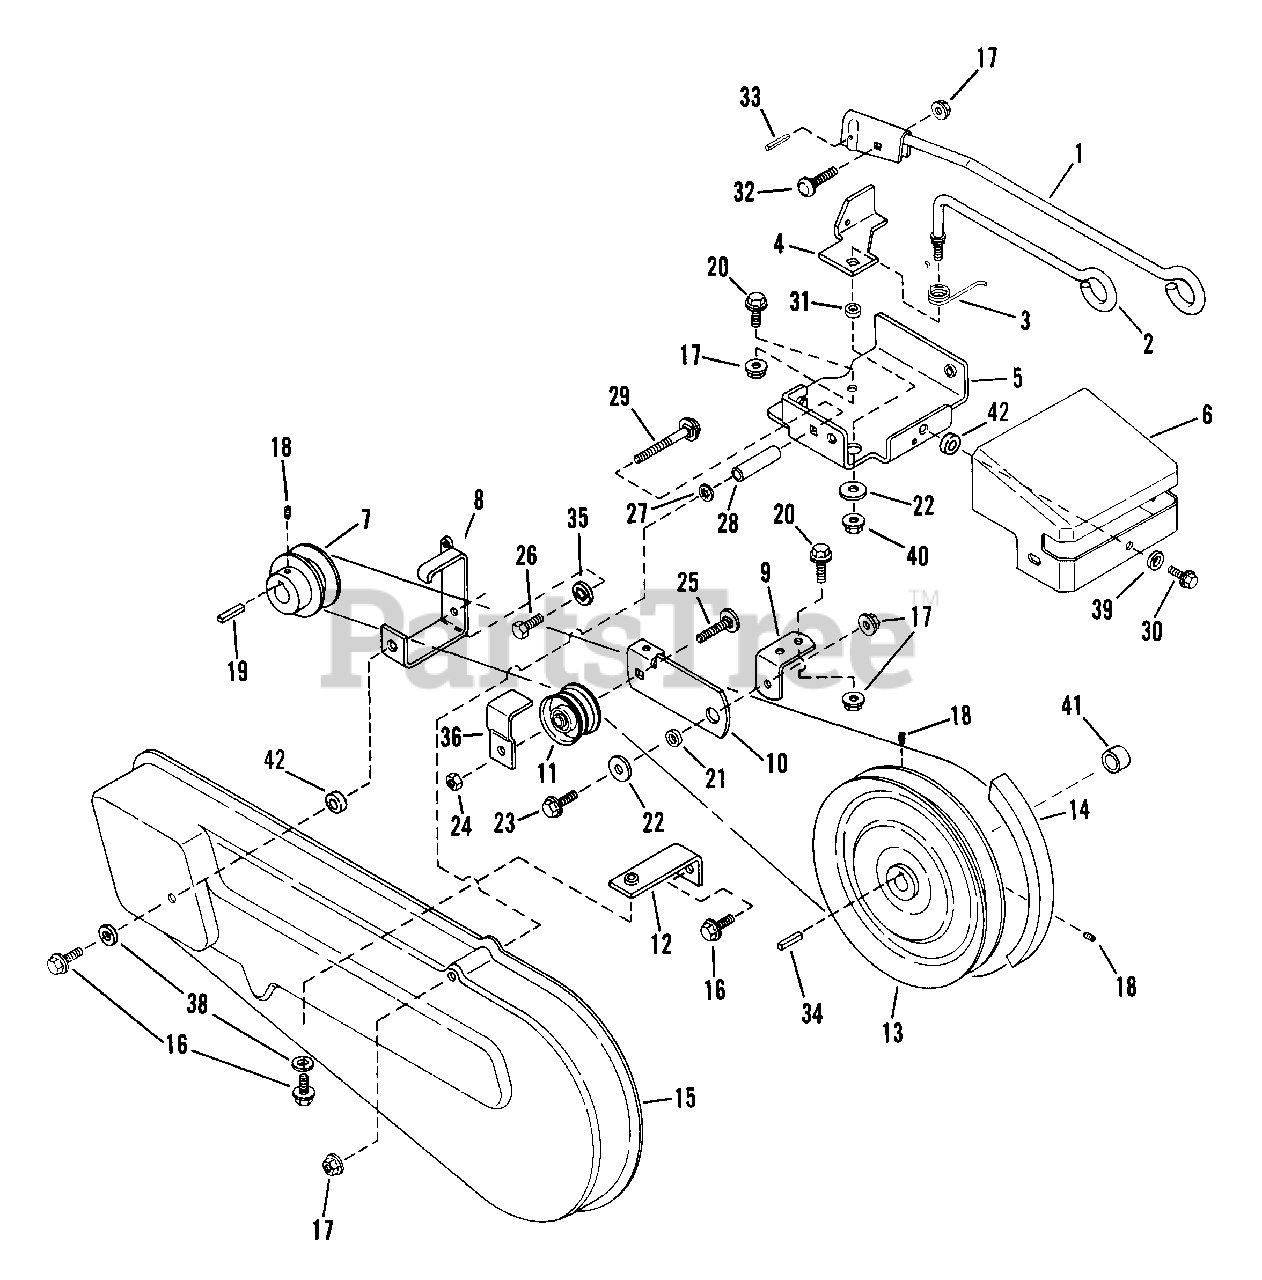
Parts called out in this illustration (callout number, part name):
1	LEVER, Shift
2	LEVER, Lockout
3	SPRING, Interlock
4	INTERLOCK, Shift
5	PLATE, Shift
6	COVER, Shift
7	PULLEY, Engine
8	GUIDE, Belt
9	BRACKET, Idler Pivot
10	BRACKET, Idler Arm
11	PULLEY, Idler
12	BRACKET, Belt Cover
13	PULLEY, Driven
14	BELT, Drive
15	COVER, Belt
16	SCREW, 5/16-18 x 1/2 Self-Tapping
17	NUT, 5/16-18 Hex Flange Lock
18	SCREW, 5/16-18 x 5/16" Hex Set
19	KEY, 3/16x3/16x1"
20	BOLT, 5/16-18x1/2" Hex Flange Lock
21	SPACER
22	WASHER, 11/32 Flat
23	BOLT, 5/16-18x3/4" Hex Flange Lock
24	NUT, 3/8-16 Hex Lock
25	BOLT, 3/8-16x1-1/2" Flat Head Carriage
26	SCREW, 5/16-24x1/2" Hex Head Cap
27	RETAINER, 5/16 Bolt
28	BUSHING
29	BOLT, 5/16-18 x 2-1/2" Short Neck Carriage
30	BOLT, 1/4-20x1/2" Self-Tapping
31	SPACER
32	BOLT, 5/16-18x1" Short Neck Carriage
33	PIN,L 3/16x1" Roll
34	KEY, 3/16x3/4" Square
35	WASHER, 5/16 Internal Tooth Lock
36	GUIDE, Idler
38	WASHER, 5/16 Flat
39	WASHER, 1/4 Flat
40	NUT, 5/16-18 Hex Flange Lock
41	SPACER, 5/8 I.D.
42	BUSHING, Rubber (IR 5002B)
